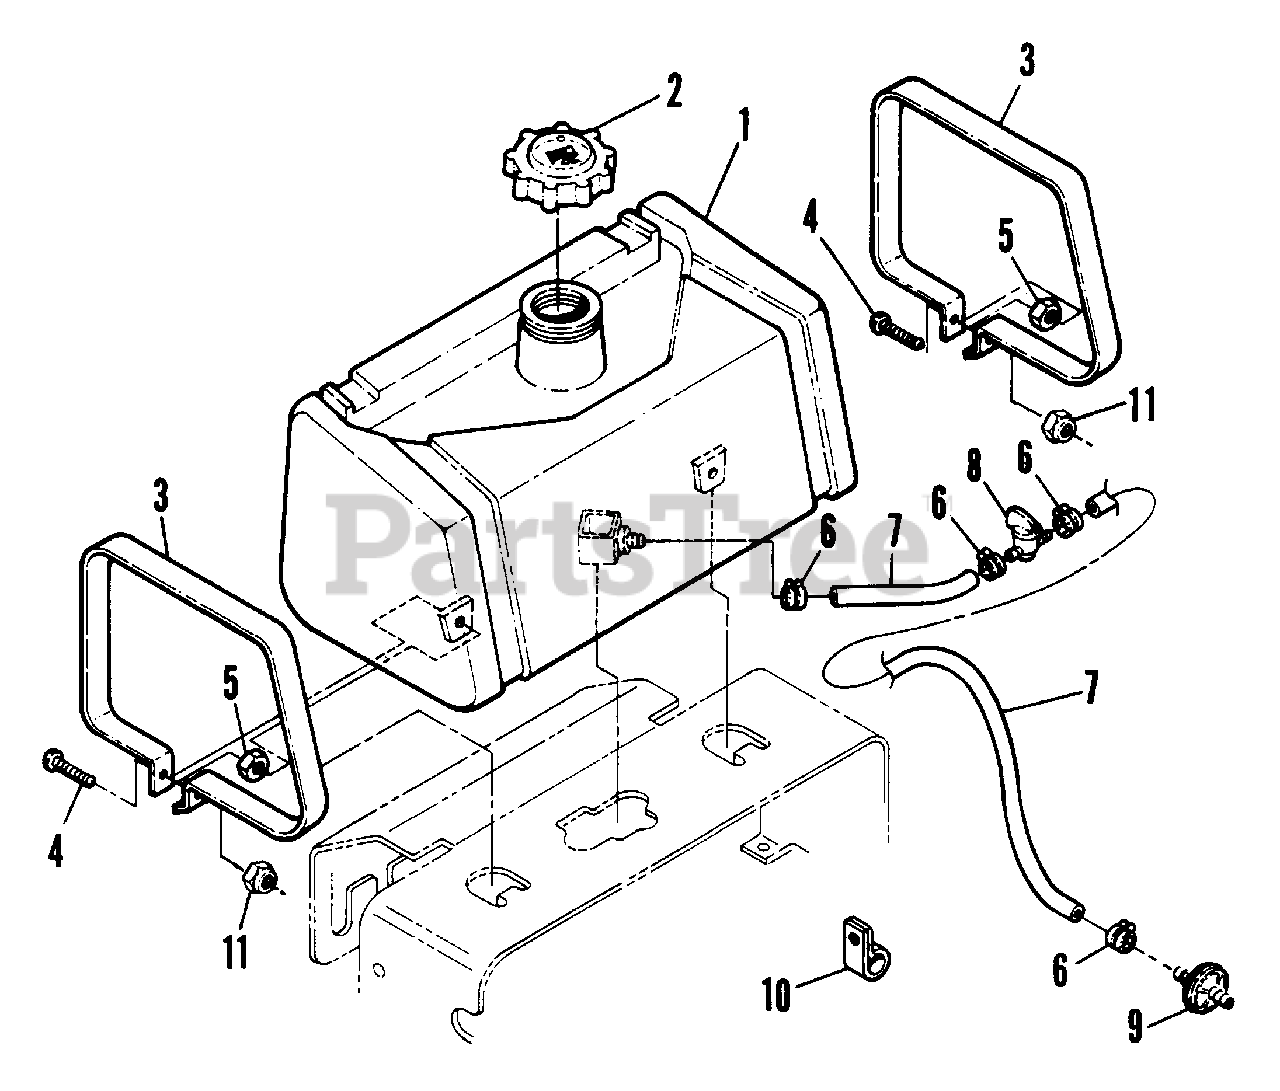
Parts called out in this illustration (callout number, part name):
1	TANK, Fuel
2	GAS CAP
3	STRAP, Tank
4	SCREW, Machine Head Phillips, #10-24 x 2
5	NUT, Keps #10-24
6	HOSE CLAMP
7	FUEL LINE, 10" (18 HP)
8	FUEL SHUT-OFF VALVE
9	FILTER, In-Line
11	NUT, #10- 24 Lock
